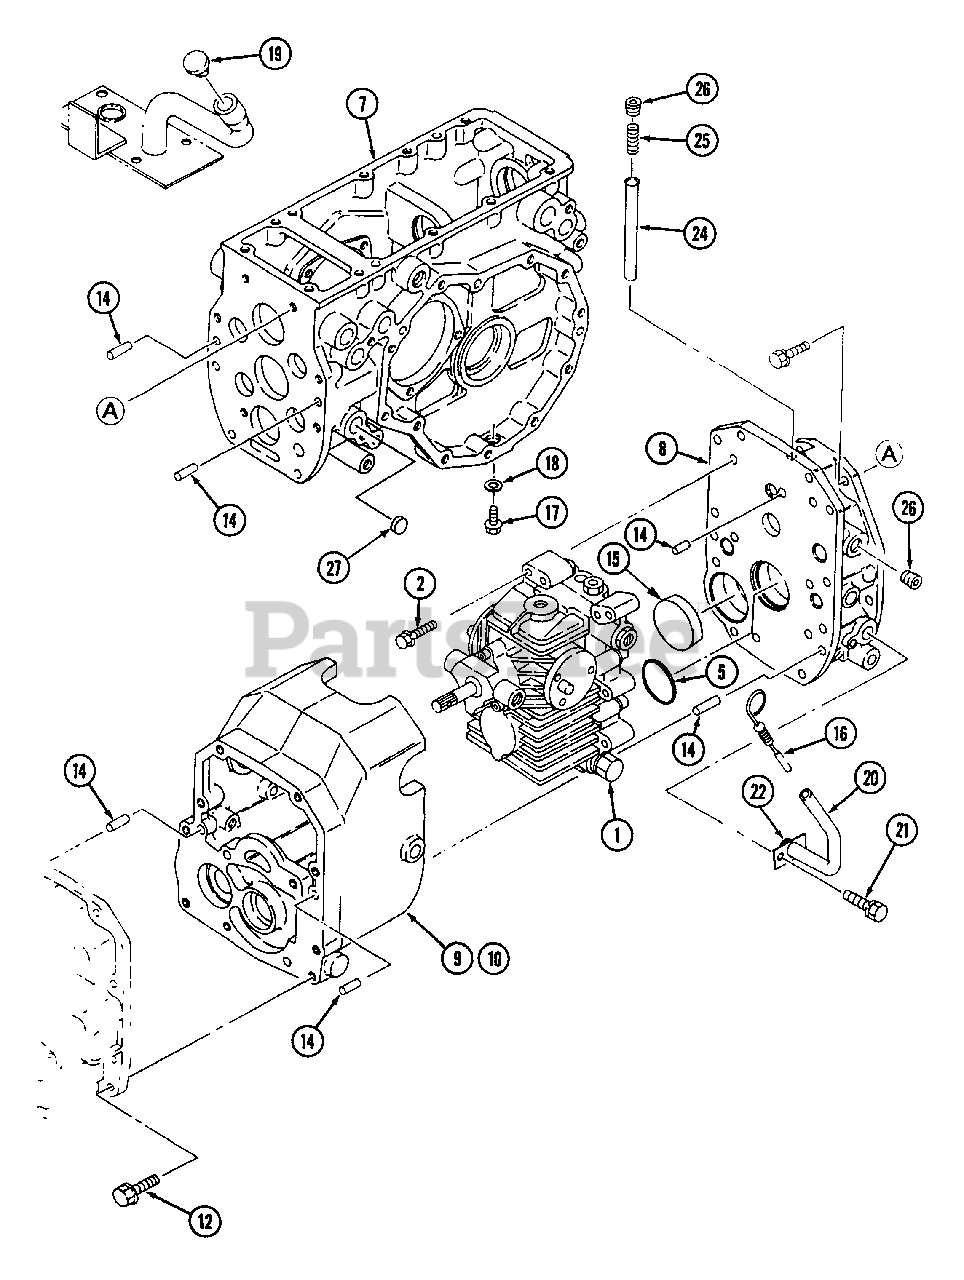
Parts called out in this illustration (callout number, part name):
1	Hydrostatic Unit
10	Cover HST
15	Seal Cap
18	Seal, Washer
22	O-Ring
27	Seal Cap
